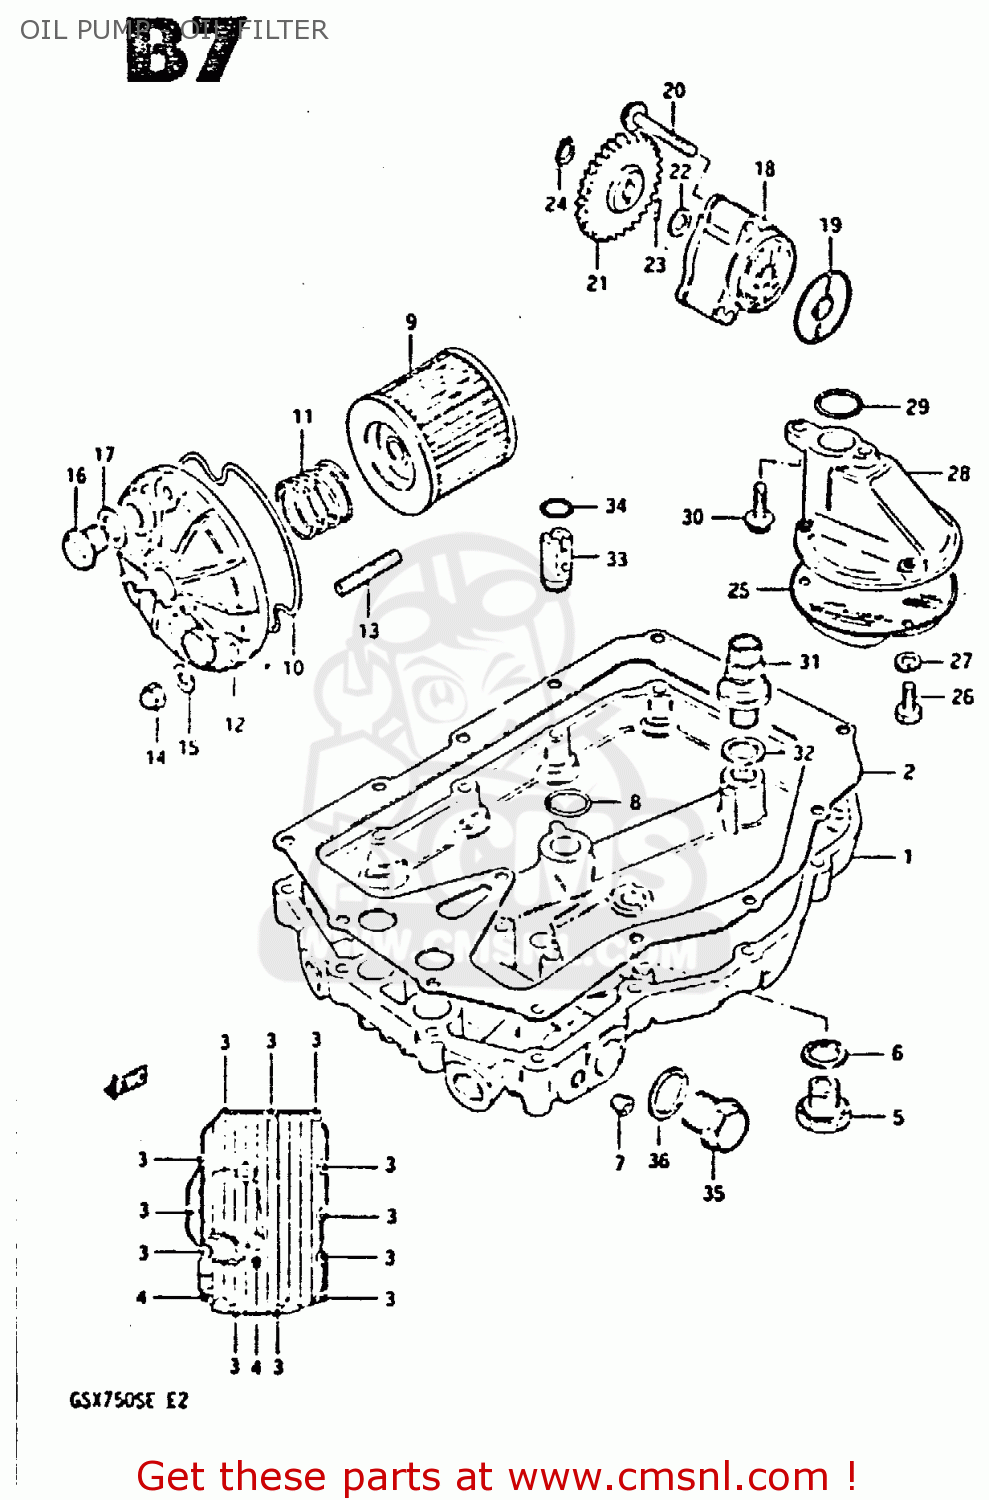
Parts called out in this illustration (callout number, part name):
1	PAN, OIL
2	GASKET,OIL PAN (MCA)
3	BOLT 6X30
4	BOLT
5	PLUG, OIL DRAIN
6	GASKET(14X19.2X2) (NAS)
7	PLUG
8	O RING(D:3.2,ID:15.8)
9	FILTER ASSY,ENGINE OIL
10	O RING,OIL FILTER CHAMBER CAP
11	SPRING
12	CAP,OIL FILTER
13	STUD 6X20
14	NUT 6MM
15	WASHER
16	PLUG(14X12)
17	GASKET(14X19.2X2) (NAS)
18	PUMP ASSEMBLY,OIL
19	O-RING,OIL PUMP
20	BOLT
21	GEAR,OIL PUMP DRIVEN
22	SHIM
23	PIN(4X15.8)
24	CIRCLIP
25	STRAINER,ENGINE OIL
26	BOLT
27	LOCK WASHER
28	PROTECTOR,OIL STRAINER
29	O RING(D:3.2,ID:17.8)
30	BOLT,REAR
31	REGULATOR ASSY,ENGINE OIL
32	WASHER
33	VALVE ASSEMBLY,PISTON OIL
34	O RING(D:1.3,ID:9.8)
35	PLUG
36	O RING(D:2.4,ID:16.8)
